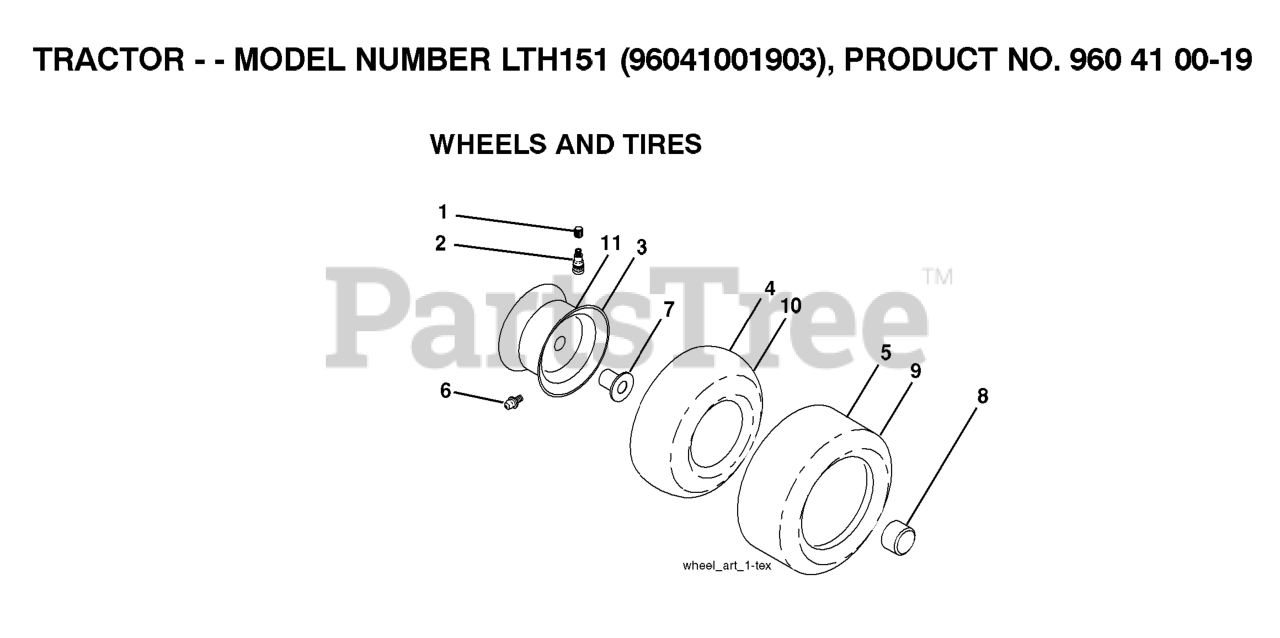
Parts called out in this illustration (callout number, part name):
2	VALVE STEM LT
3	RIM ASM 6" FRONT SILVER
4	TUBE.5.3/4.5/6
5	TIRE HEAVY DUTY
6	FITTING LT
7	BEARING T
8	CAP, AXLE BLK
9	TIRE HEAVY DUTY
10	TUBE
11	RIM ASM 8" REAR SILVER
